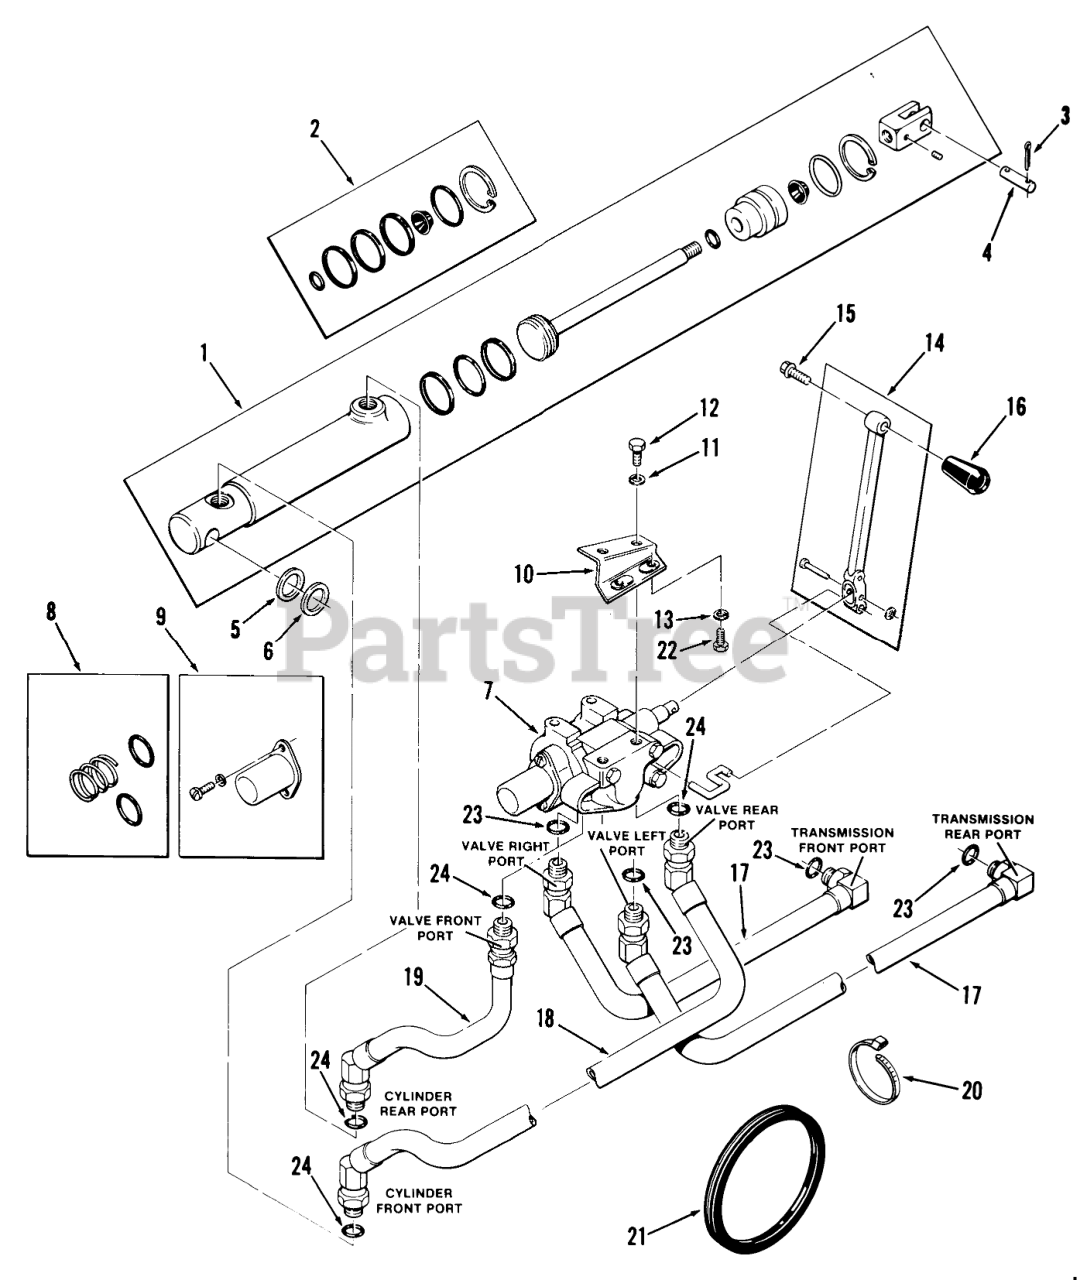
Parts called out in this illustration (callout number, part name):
2	S/A O-RING&GASKET AS
5	WASHER
13	WASHER 5/16 SAE
15	SCREW
21	GROMMET
24	O-Ring C-161, C-14, C-161 Twin Only
